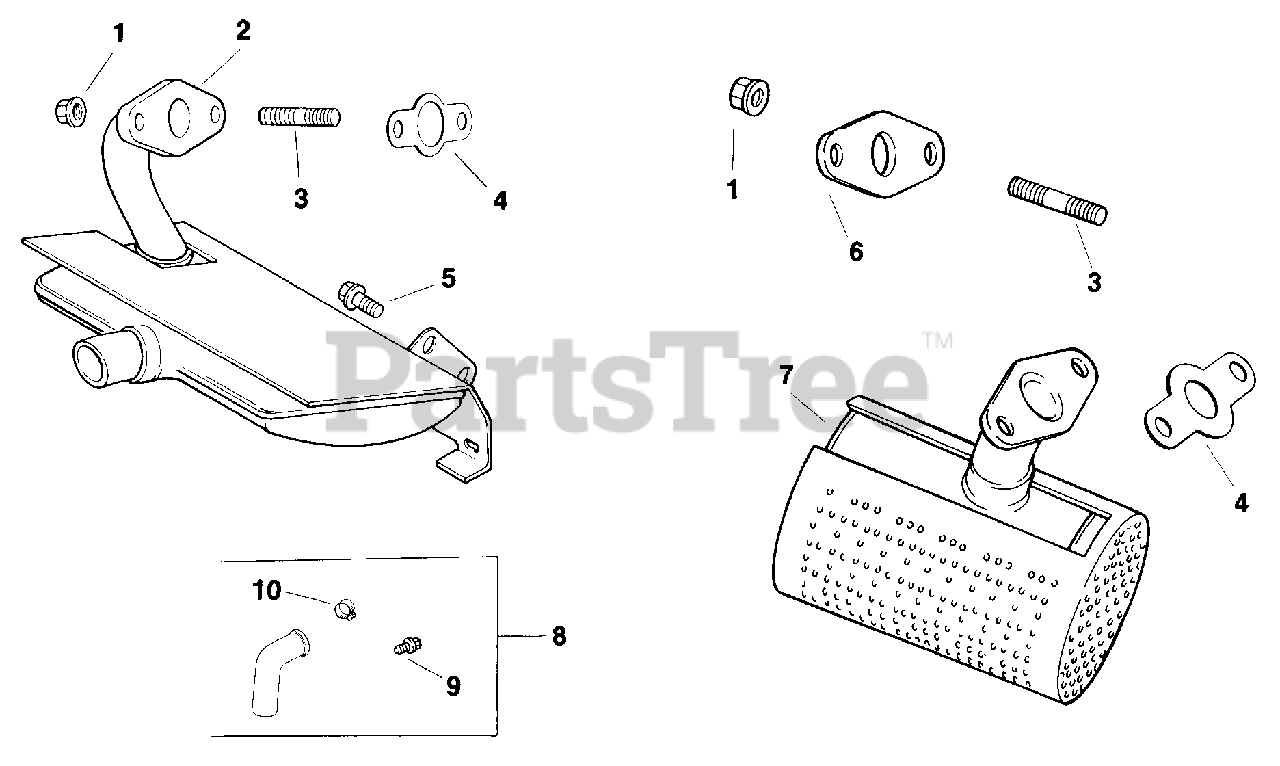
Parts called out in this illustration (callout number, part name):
1	Nut M8x1.25
2	MUFFLER - DISCONTINUED
3	Stud M8x1.25x35.5
4	GASKET, EXHAUST
5	SCREW - USE M-0645016
8	KIT, EXHAUST DEFLECTOR - (#DSC)
9	SCREW - USE X-67-46
